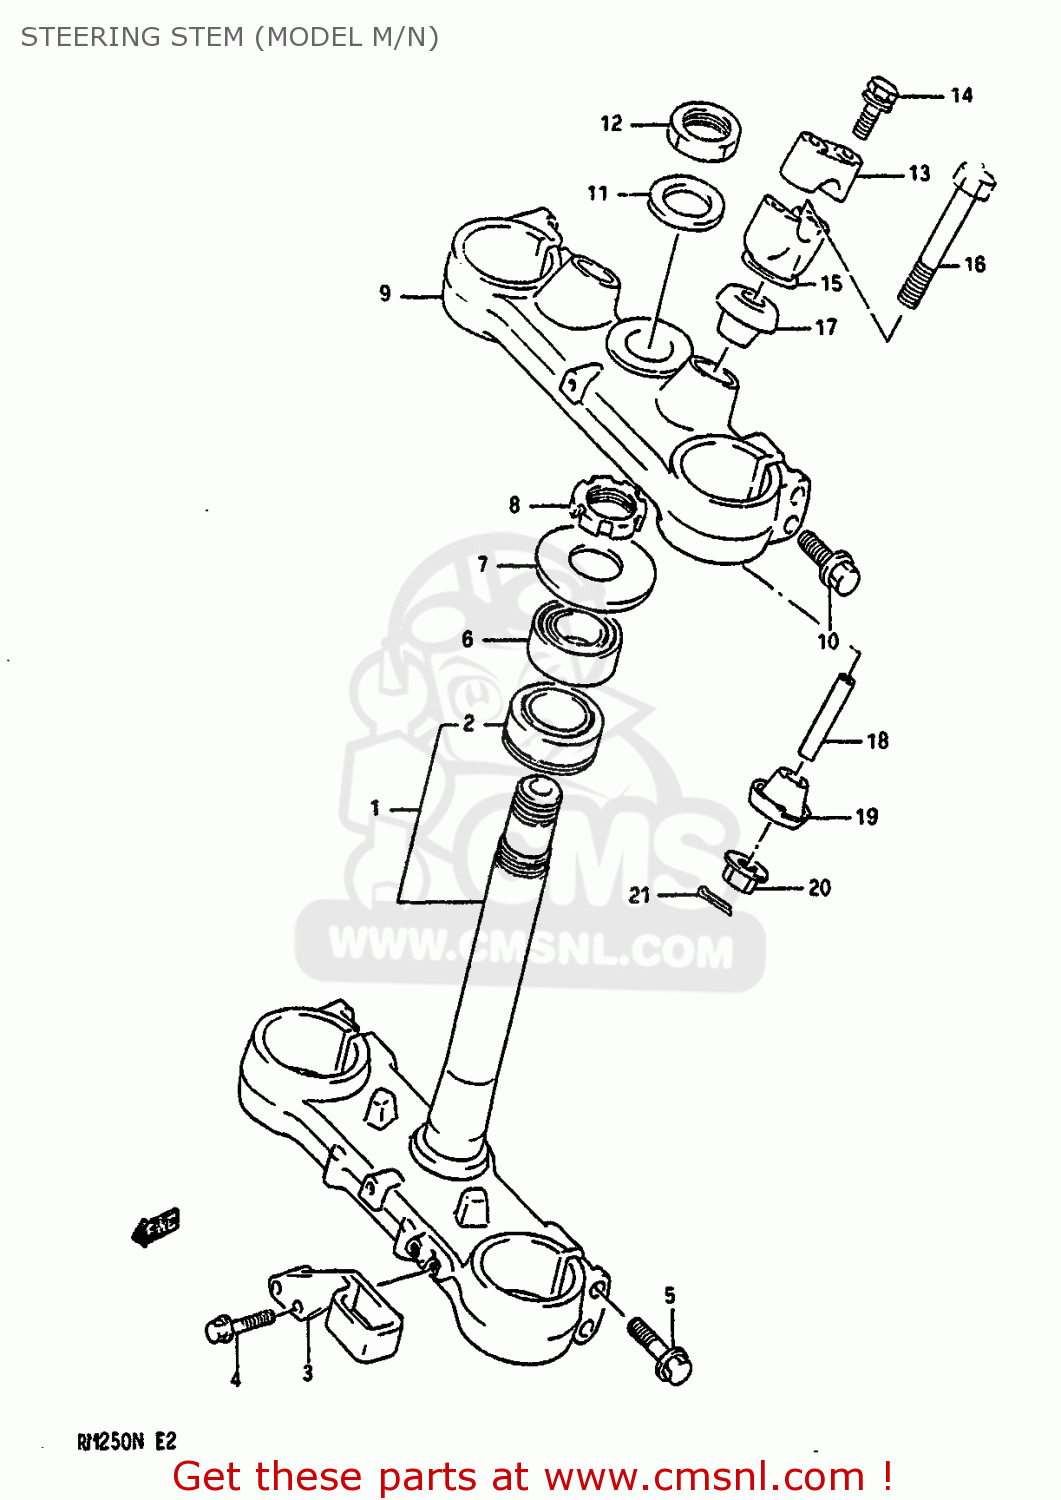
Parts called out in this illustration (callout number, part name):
1	STEM,STEERING
2	BEARING(30X52X16)
3	GUIDE,HOSE
4	BOLT,GUIDE
5	BOLT,STEM 8X45
6	BEARING
7	SEAL,STEERING
8	NUT,STEERING
9	HEAD,STEERING STEM
10	BOLT,STEM 8X45
11	WASHER,STEM HEAD
12	NUT,STEM HEAD
13	HOLDER,HANDLEBAR
14	BOLT,HANDLE HOLDER(8X35)
15	HOLDER,HANDLE UNDER
16	BOLT,LWR HOLDER
17	CUSHION,RUBBER UPR
18	SPACER
19	DAMPER,LWR
20	NUT
21	NUT
22	COTTER PIN
